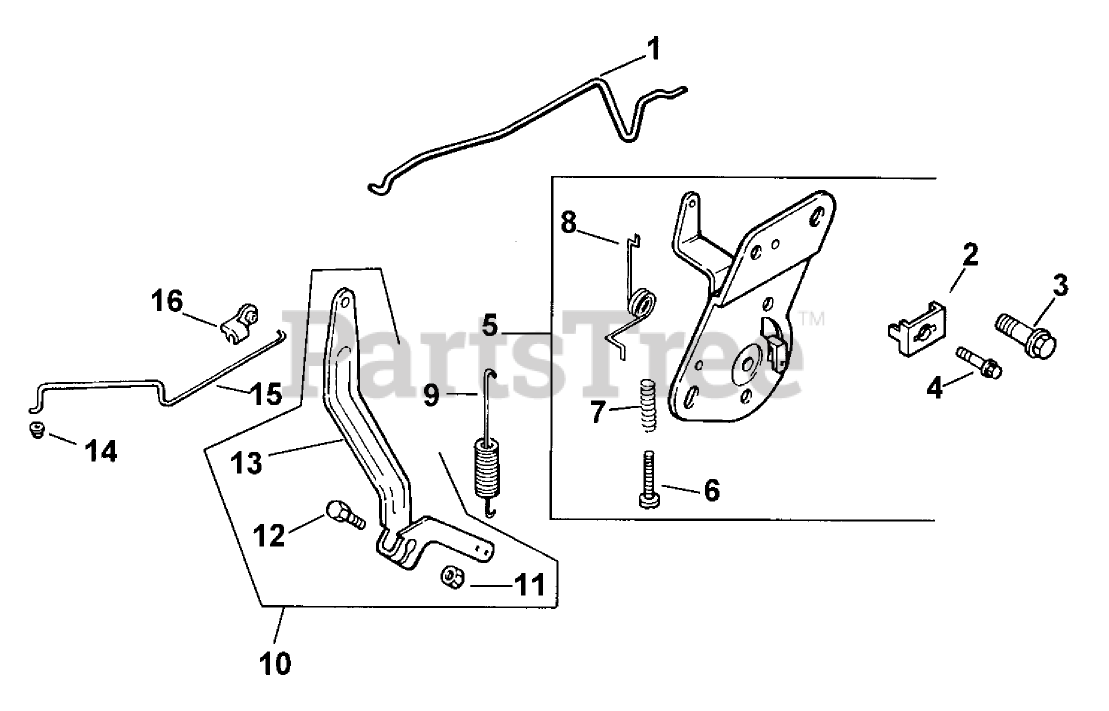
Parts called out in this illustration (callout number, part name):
1	Linkage Choke
2	Clamp
3	Screw Socket
4	Screw
5	Control-Speed
6	Screw
7	Spring
8	Spring Choke
9	Spring-Governor
10	Kit-Governor Lever (Incl. Ref.#11-13)
11	Nut
12	Bolt
13	Lever-Governor
14	Bushing-Linkage
15	Linkage-Throttle
16	Bushing-Linkage
